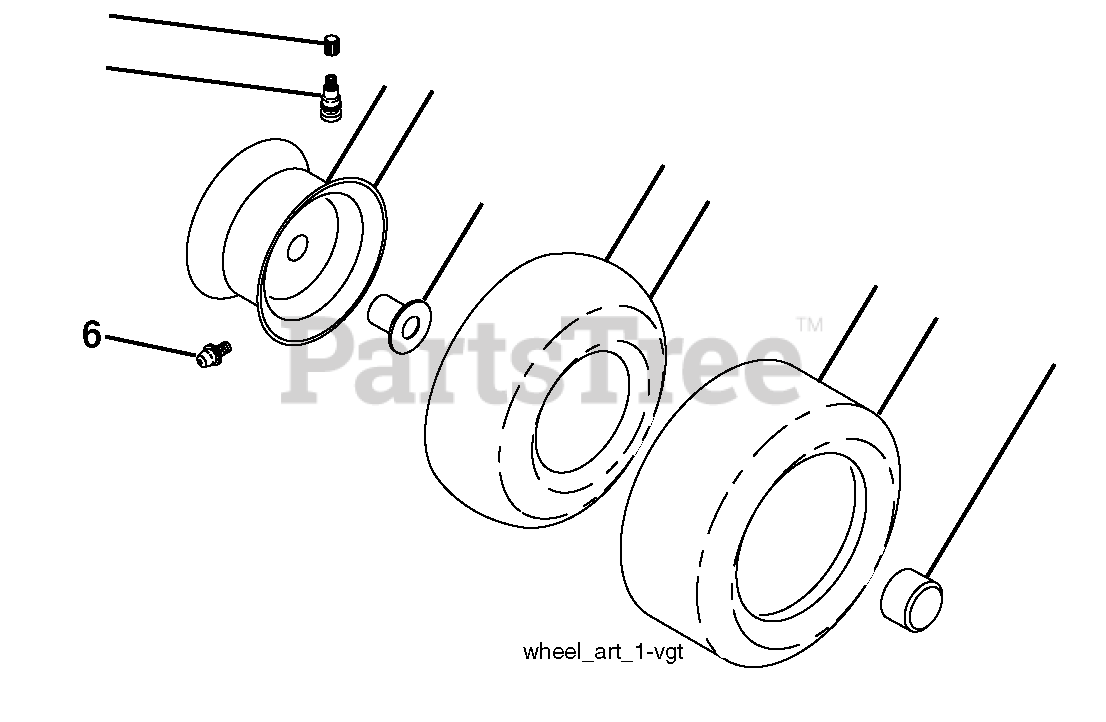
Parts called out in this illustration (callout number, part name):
1	Cap, Valve, Tire
2	Stem, Valve
3	Rim Assembly, Front
4	Tube, Front
5	Tire, Front
6	Fitting, Grease
7	Bearing, Flange
8	Cap, Axle
9	Tire, Rear
10	Tube, Rear
11	Rim Assembly, Rear
11	Sealant, Tire (10 oz. Tube)
